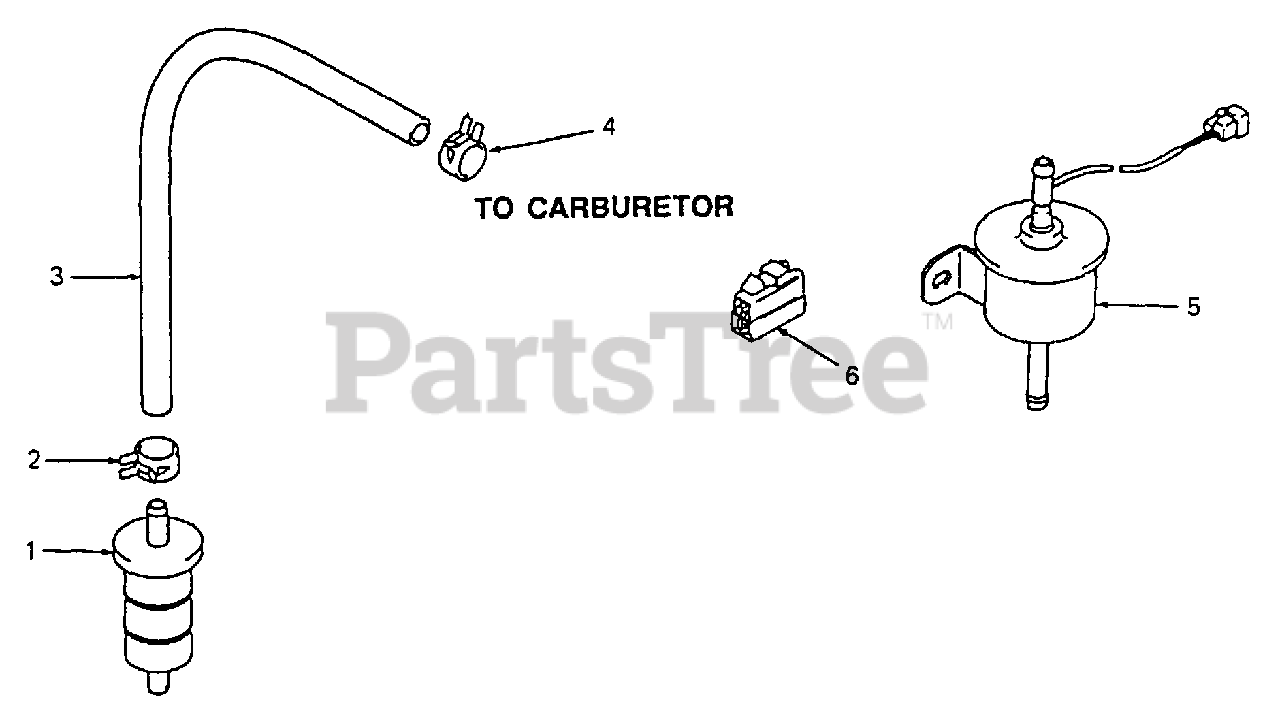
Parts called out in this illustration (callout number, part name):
1	Filter, Fuel
3	Tube, Braided
6	Connector, Cord
